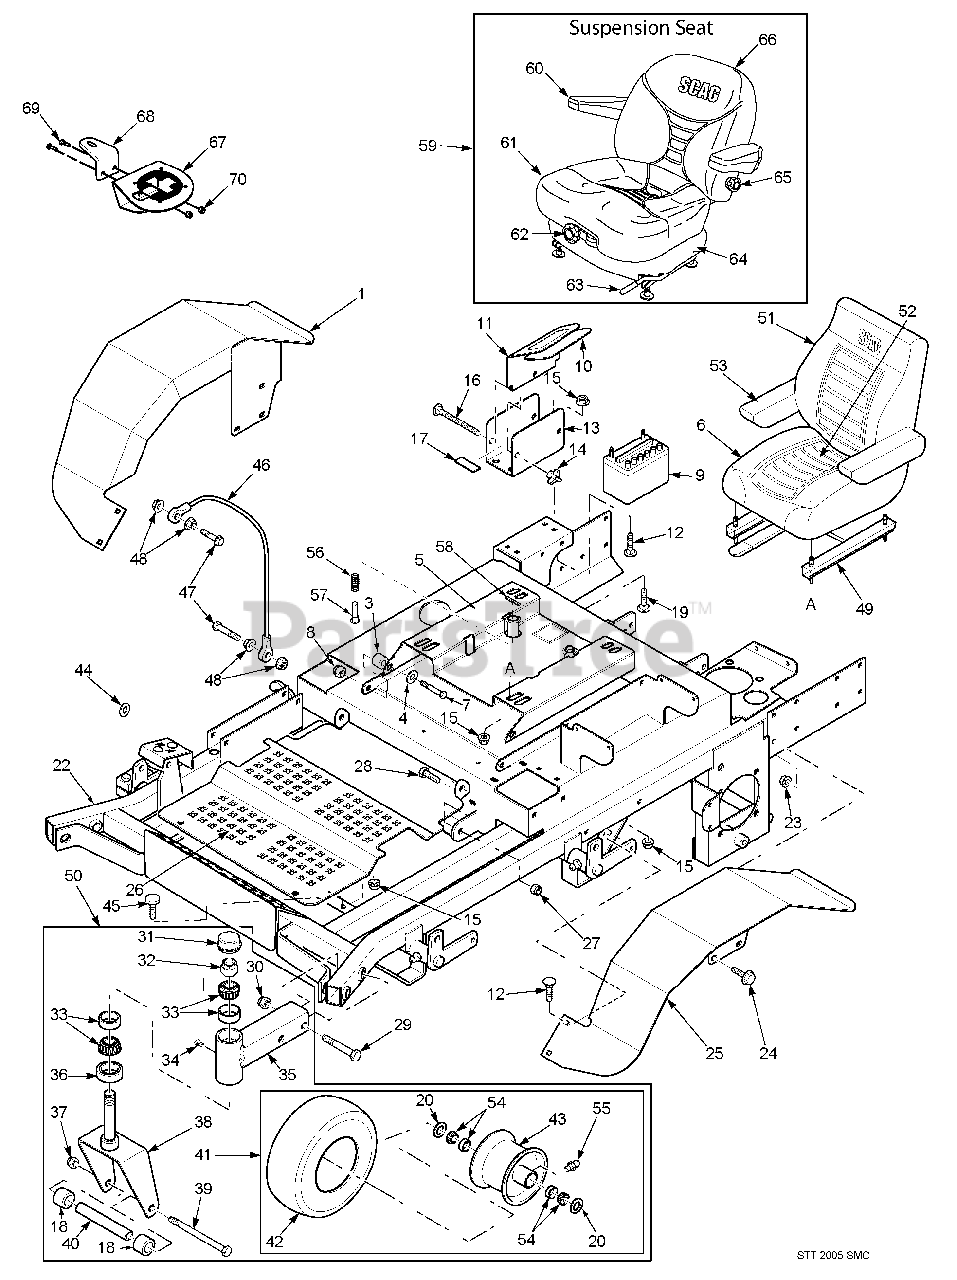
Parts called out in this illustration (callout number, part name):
1	Fender Weldment, RH
2	Bolt, Hex Head, 5/16-18 x 1, Zinc
3	Spacer
4	Flatwasher, 3/8-.391 x .938 x .105
5	Seat Plate Weldment
6	Seat Assembly w/armrest
7	Bolt, Hex Head 3/8-16 x 2.0"
8	Nut, Elastic Stop 3/8-16
9	Battery
10	Pad, Battery Cover
11	Cover, Battery
12	Bolt, Carriage 5/16-18 x 3/4"
13	Plate, Battery Box
14	Wing Nut, 1/4-20 x 3/4"
15	Nut, Hex Serrated Flange 5/16-18
16	Bolt, Carriage 1/4-20 x 6"
17	Rubber Pad
18	Spacer, Caster Wheel
19	Bolt, Carriage 5/16-18 x 1"
21	Lock Nut, 3/8-16, Elast. Stop
22	Main Frame
23	Nut, Hex Serrated Flange 3/8-16
24	Screw, Hex Serrated Flange 3/8-16 x 1"
25	Fender Weldment, LH
26	Foot Plate
27	Nut, Hex Elastic Stop 3/8-16
28	Bolt, Hex Head 3/8-16 x 1"
29	Bolt, Hex Head 5/8-11 x 4"
30	Nut, Hex Elastic Stop 5/8-11
31	Cap, Grease
32	Nut, Hex Elastic Stop 1.0-14
33	Bearing W/Race
34	Plug, 1/4-28 THD Form
35	Extention Weldment, Caster 52A (LH)
36	Seal, 2.00 OD. x 1.625 Bore
37	Nut, Hex Elastic Stop 1/2-13
38	Yoke Weldment, Caster (52A)
39	Bolt, Hex Head 1/2-13 x 7-1/2" (52A)
40	Sleeve, Caster Wheel (52A)
41	Wheel Assy, 52A
42	Tire, 13 x 5.00 4-Ply (52A)
43	Rim Assembly, 52A
44	Flatwasher, 3/8"-.391 x .938 x .105
45	Bumper, Rubber
46	Cable, Seat Stop
47	Bolt, Hex Head 1/4-20 x 1-1/4"
48	Nut, Hex Serrated Flange 1/4-20
49	Seat Adjustment, Track Set
50	Caster Wheel Assy 52A (RH)
51	Back Cushion Cover
52	Seat Cushion Cover
53	Arm Rest, Right Hand
54	Bearing w/ Race
55	Grease Fitting
56	Spring, Seat
57	Pin Retainer, Spring
58	Roll Pin, Spring 5/32 x 3/4"
59	Suspension Seat Assembly
60	Armrest Only
61	Seat Cusion Kit Seat Drain Kit
62	Weight Adjustment Kit
63	Seat Adjustment, Track Set
64	Shock Absorber Kit
65	Lumbar Kit
66	Back Cusion Kit
67	Cup Holder Assembly
68	Mounting Bracket, STT Cup Holder
69	Bolt, Hex Head 1/4-20 x 3/4"
70	Nut, Elastic Stop 1/4-20
